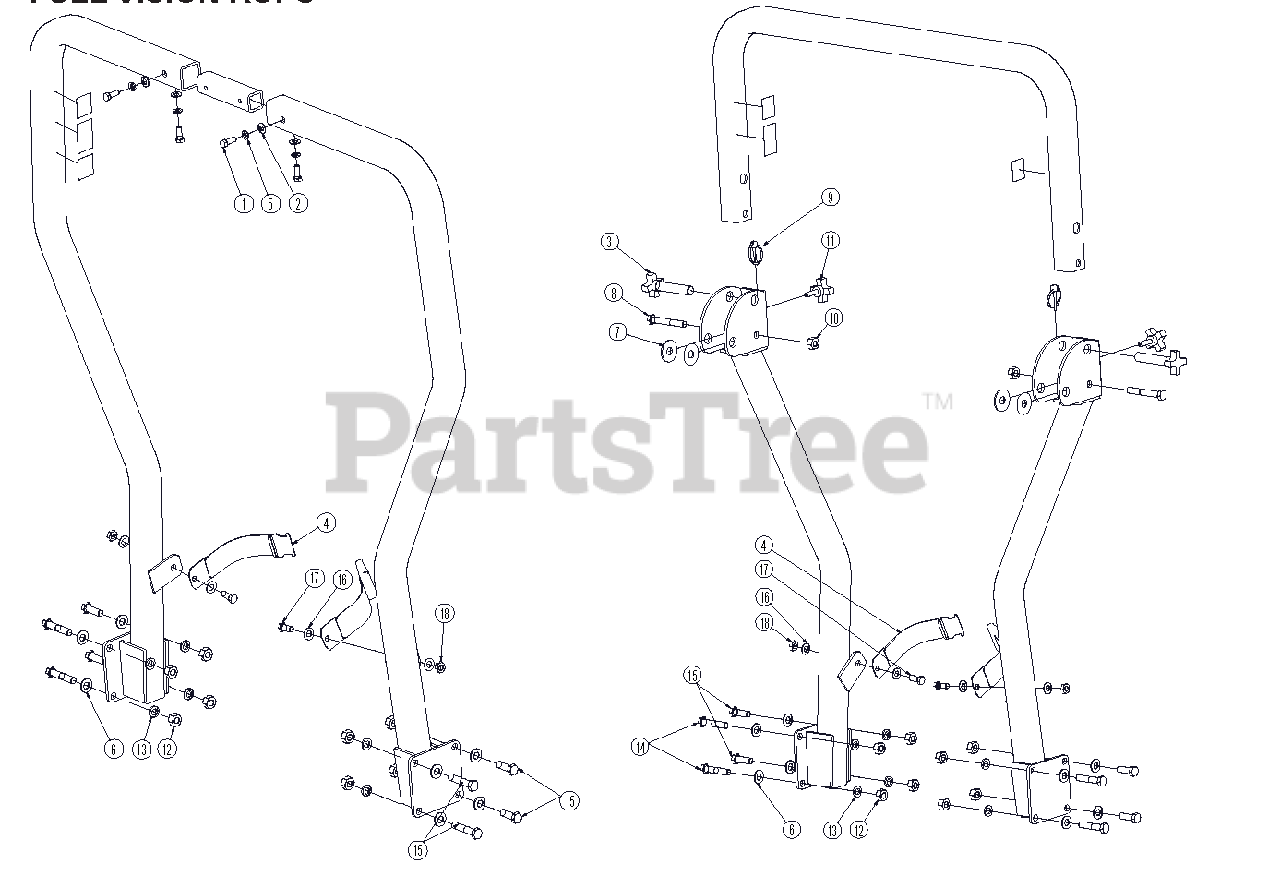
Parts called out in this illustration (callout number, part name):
1	BOLT, 3/8-16X1.00 HEX 5 Y
2	WASHER, .375 REG FLAT Y
3	PIN ASSEMBLY S/O
4	SEAT BELT ASSY
5	WASHER, .375 MED SPRG LOCK Y
6	WASHER, .500 REG FLAT Y
7	WASHER, UHMW.56IDX1.25ODX.20TH
8	BOLT, 1/2-13X3.50 HEX 5 Y
9	PIN, LNC .188X1.25 Y
10	LOCKNUT, 1/2-13 CENTER Y
11	KNOB W/ STUD 3/8-16 X 1.5 S/O
12	NUT, 1/2-13 STD HEX GR5 Y
13	WASHER, .500 MED SPRG LOCK Y
14	BOLT, 1/2-13X2.50 HEX 5 Y
15	BOLT, 1/2-13X1.50 HEX 5 Y
16	FLATWASHER, 7/16 REG
17	BOLT, 7/16-20X1.00 HEX 5 Y
18	LOCKNUT, 7/16-20 CENTER Y
